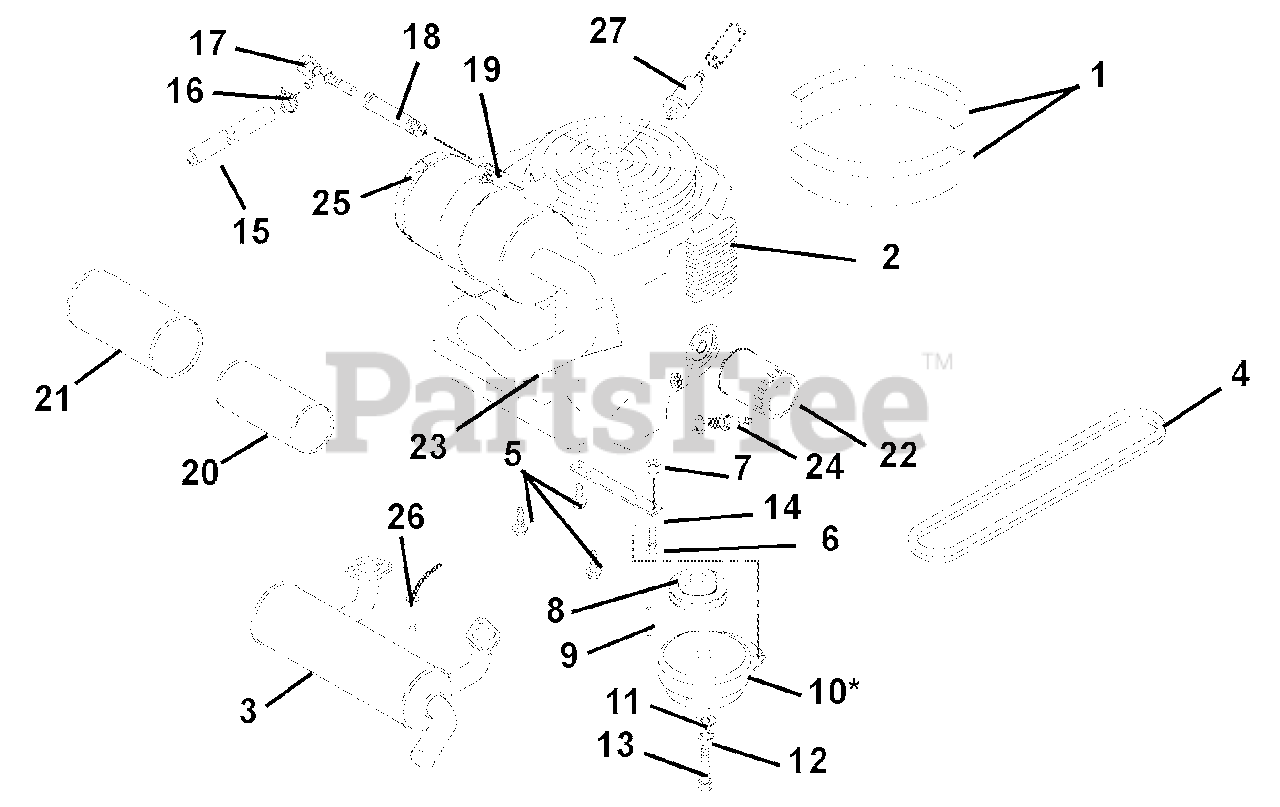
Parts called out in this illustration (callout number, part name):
1	Seal, Foam
2	Engine, Kohler 28HP EFI (048)
3	Muffler, Kohler EFI (048)
4	Belt, Poly-V
5	Screw, Tapping Hex Washer Head .38-16 x 1.00
6	Bolt, Hex .31-18 x 1.75 Grade 5
7	Nut, Locking Top Flange .31-18
8	Sheave, Poly V 1.127 x 3.25
9	Key, Square .25 x 1.00 x .25
10	Clutch, Electric
11	Washer, Flat Steel .515 x 1.625 x .250
12	Washer, Locking .44 x .109
13	Bolt, Hex .44-20 x 3.00 Grade 5
14	Anchor, Clutch
15	Gas Line, Bulk .25 ID (045, 046, 047, 049, 052, 053)
16	Hose, Clamp
17	Cock, Oil Drain
18	Adapter, Oil Drain
19	Bracket, Air Cleaner Mount
20	Element, Inner Safety
21	Element, Outer Primary
22	Oil Filter (047, 048, 052, 053)
23	Hose, Air Intake (047, 048, 052, 053)
24	Spark Plug (047, 048, 052, 053)
25	Assembly, Air Cleaner
26	Sensor, Oxygen (048)
27	Fuel Filter (045, 046, 049)
